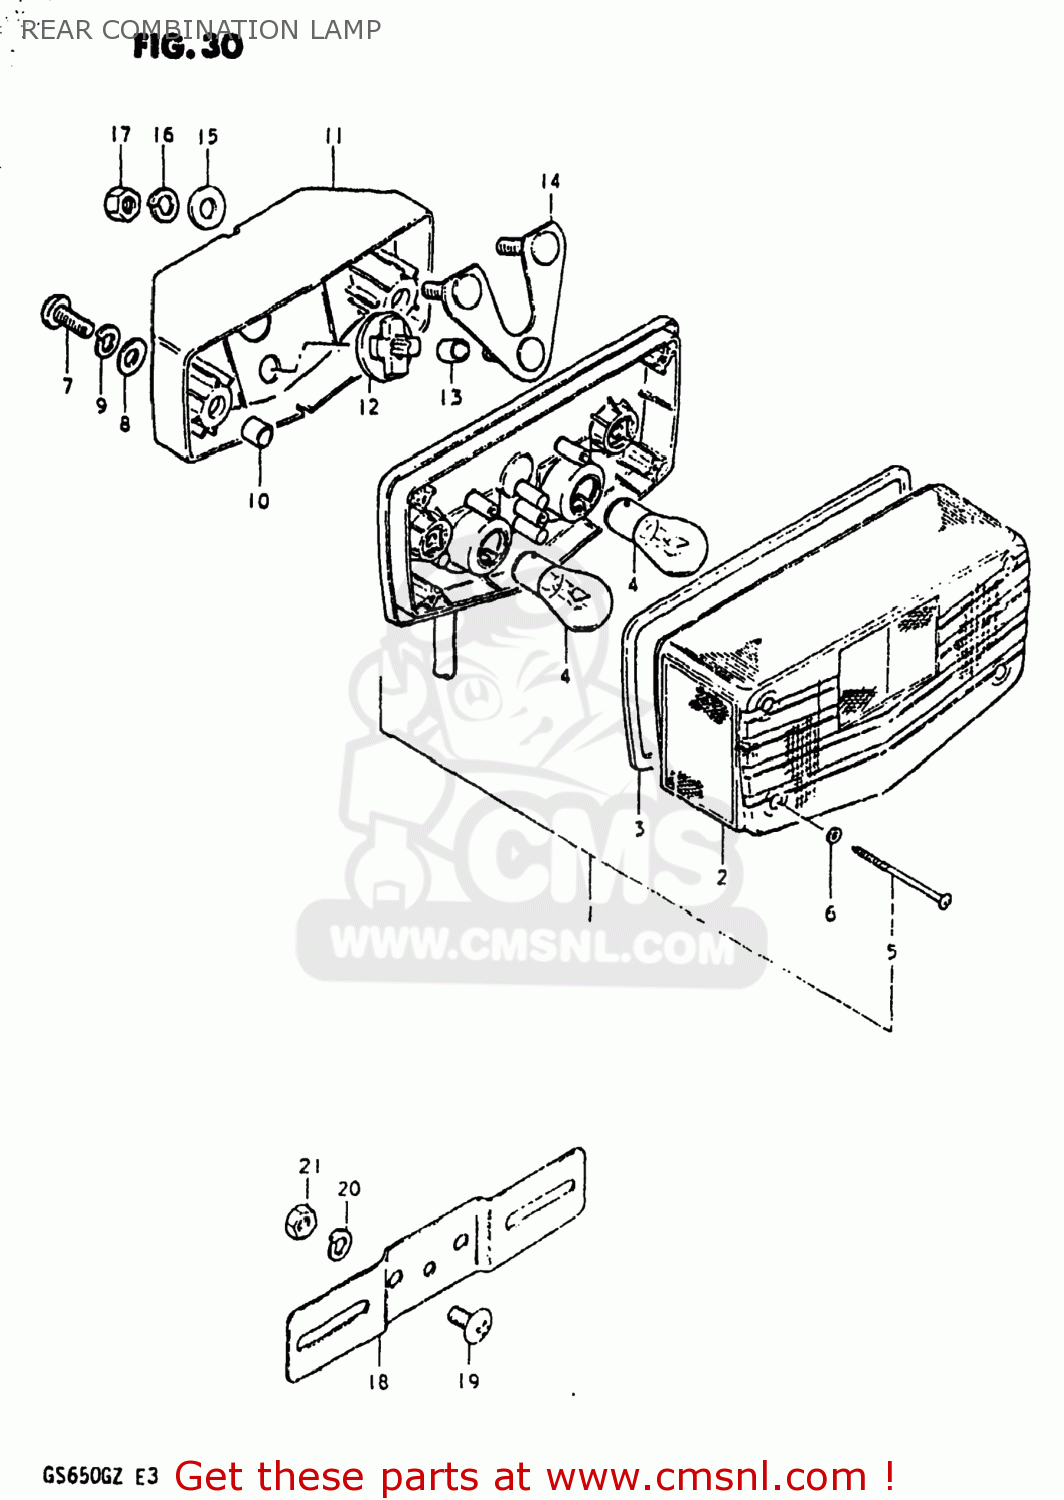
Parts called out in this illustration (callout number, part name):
1	LAMP UNIT,REAR COMBINATION
2	LENS,REAR COMBINATION LAMP
3	GASKET,REAR COMBINATION LAMP LENS (NAS)
4	BULB(12V23W)
5	SCREW
6	GASKET (NAS)
7	SCREW
8	WASHER
9	LOCK WASHER
10	SPACER,REAR COMBINATION LAMP
11	BRACKET UNIT,TAIL LAMP
12	CUSHION,REAR COMBINATION LAMP
13	SPACER,REAR COMBINATION LAMP
14	PLATE,REAR COMBINATION LAMP
15	WASHER
16	LOCK WASHER
17	NUT
18	PLATE,REAR LICENSE
19	SCREW
20	LOCK WASHER
21	NUT
